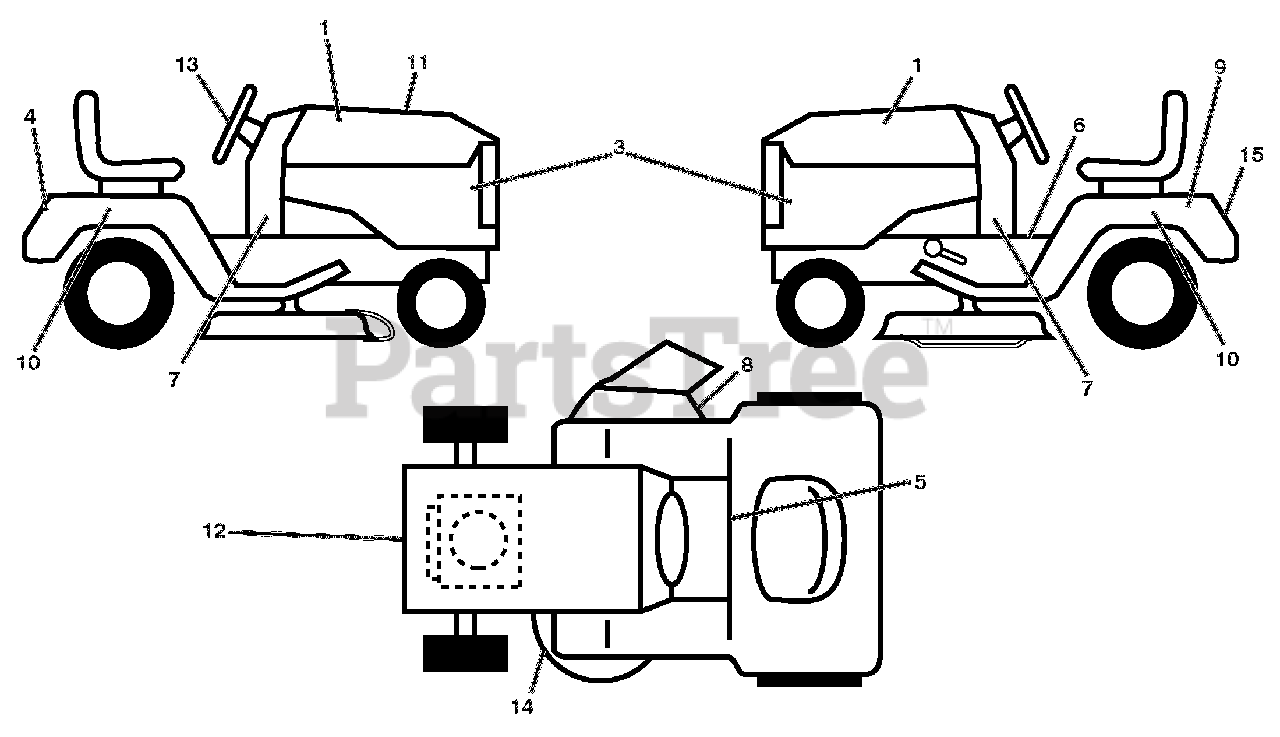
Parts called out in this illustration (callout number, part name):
1	DECAL.HOOD.RH.PRECISION.ARIENS
3	DECAL.SDPNL.PWRDBY B&S.ARIENS
4	DECAL.FENDER.REAR.ARIENS
5	DECAL.FENDER
6	DECAL, WARNING START INST.
7	DECAL DASH LOWER
8	DECAL.MOWER.WARN.KEEP HAND AWY
9	DECAL.BAT.DAN/POI P/L SYM.WPN
10	DECAL.FENDER.SIDE.HYDRO.ARIENS
11	DECAL, REPLACEMENT
12	DECAL ENGINE
13	DECAL.WHEEL.STEER.ARIENS
14	DECAL.V-BELT.SCH.42/46"MEC/ELE
15	Decal Fender Service
